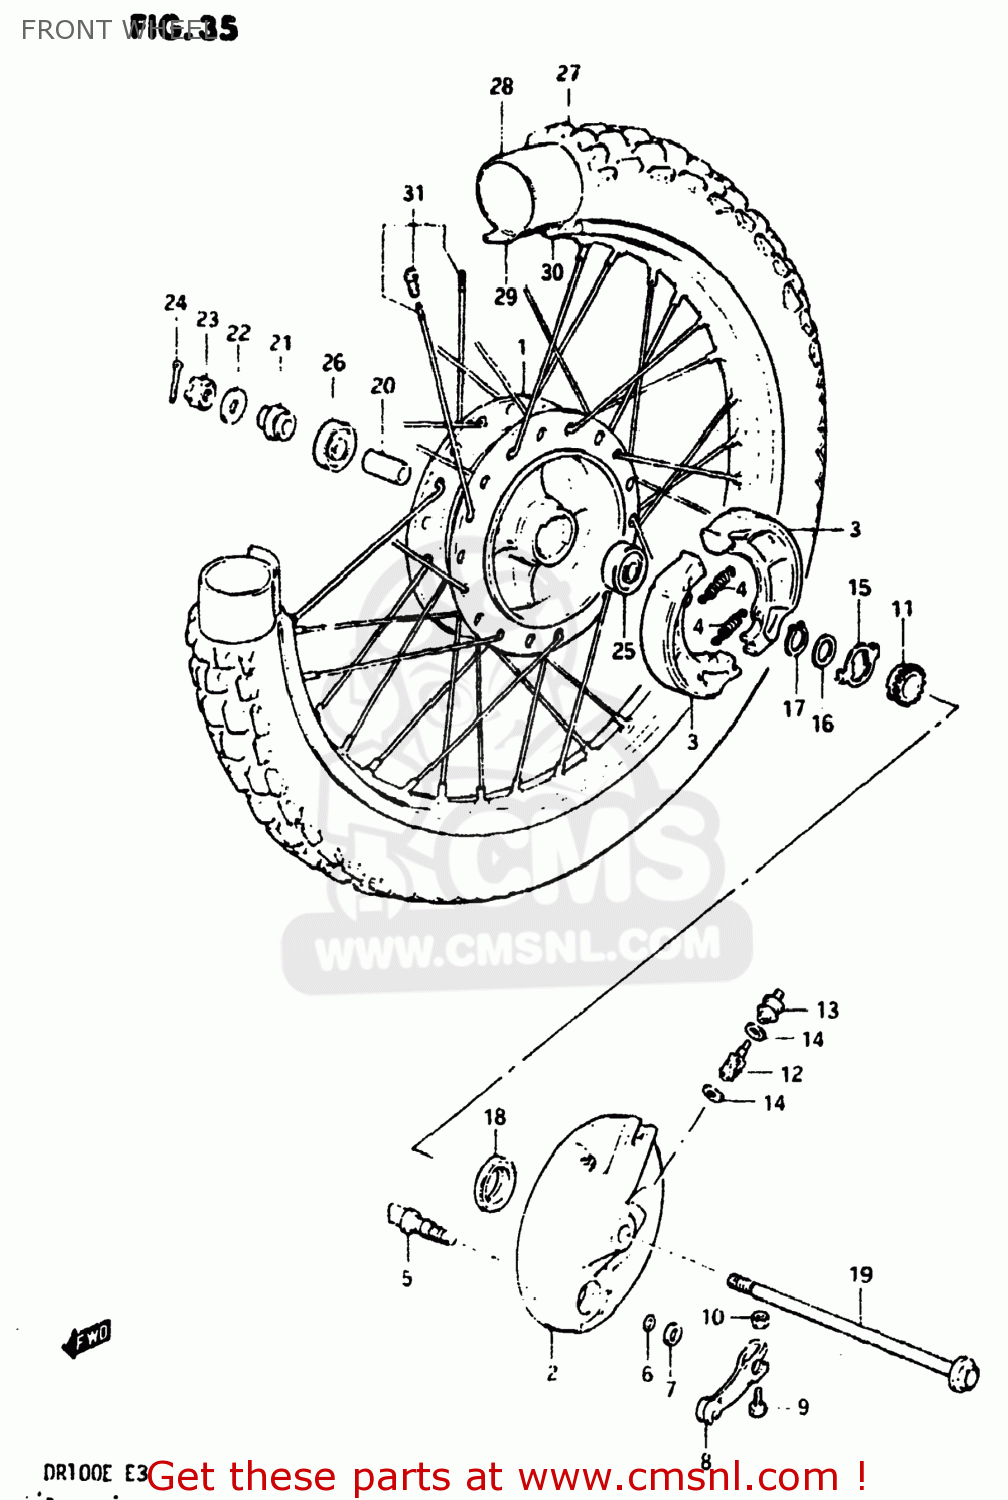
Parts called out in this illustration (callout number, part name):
1	DRUM,FRONT HUB
2	PANEL,FRONT HUB
3	SHOE,BRAKE
4	SPRING(L:34)
5	CAM,FRONT BRAKE
6	O-RING (D:2.4 ID:13.8)
7	WASHER (14.5X22X1.6)
8	LEVER,FR BRAKE CAM
9	BOLT 6X35
10	NUT
11	GEAR,SPEEDOMETER
12	PINION,SPEEDOMETER
13	BUSH,SPEEDOMETER PINION OUTER
14	WASHER (5.1X9X0.4)
15	DRIVER,SPEEDOMETER GEAR
16	WASHER(18.5X24X1)
17	CIRCLIP
18	OIL SEAL (43X58X7)
19	AXLE,FRONT
20	SPACER (12.6X19X52)
21	SPACER,FRONT AXLE,RIGHT
22	WASHER
23	NUT 12MM
24	COTTER PIN
25	BEARING
26	BEARING, RH
27	TIRE 2.75-17
28	TUBE,INNER
29	PROTECTOR,WHEEL,INNER
30	RIM,FRONT WHEEL
31	SPOKE SET,FRONT
